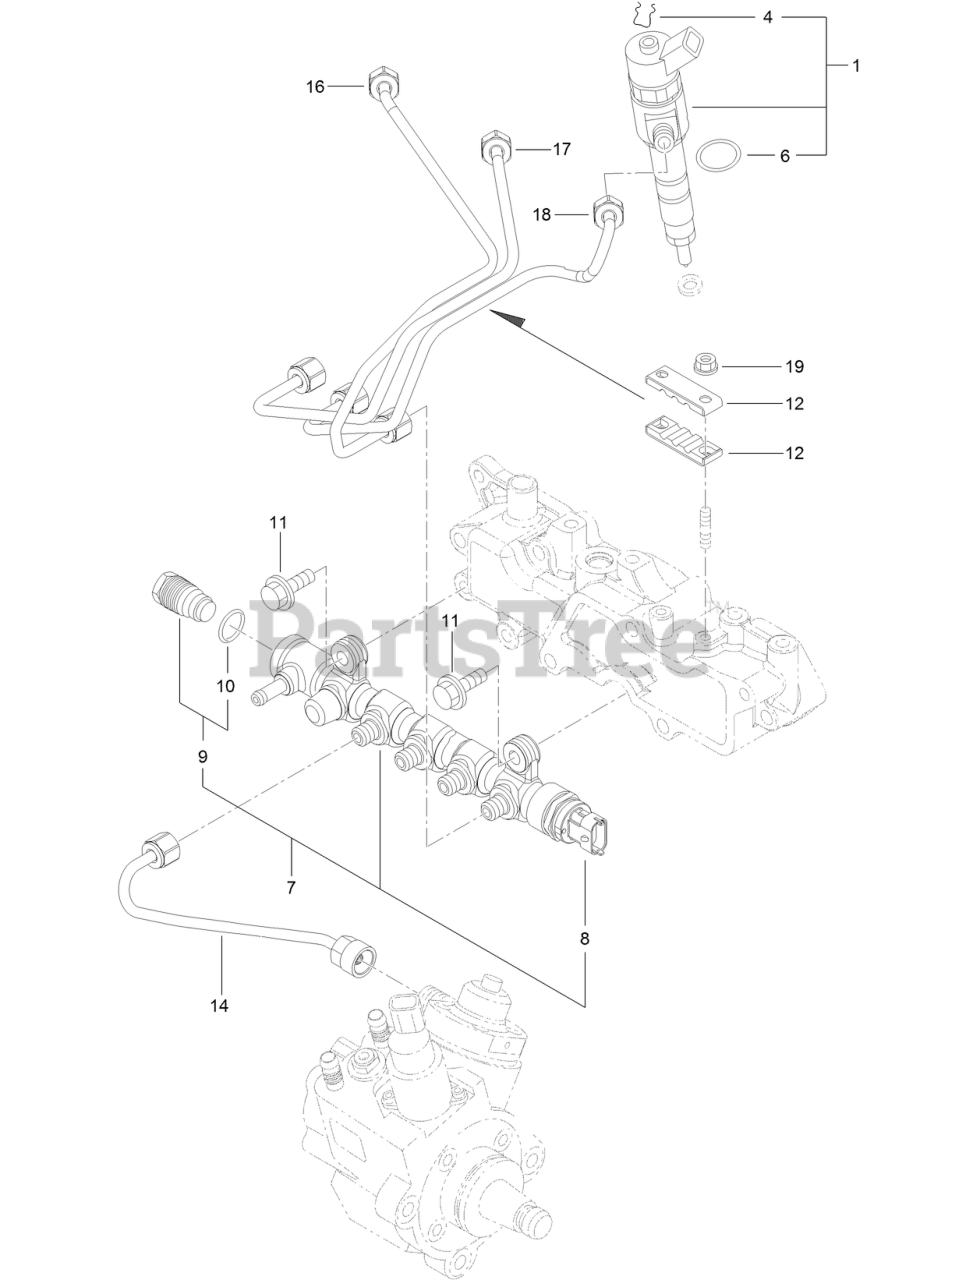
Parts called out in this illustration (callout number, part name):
1	INJECTOR ASM
4	RING-RETAINING
6	O-RING
7	RAIL ASM
8	SENSOR-PRESSURE, RAIL
9	VALVE ASM
10	O-RING
12	RETAINER
14	RAIL IN PIPE ASM
16	INJECTION PIPE ASM
17	INJECTION PIPE ASM
18	INJECTION PIPE ASM
